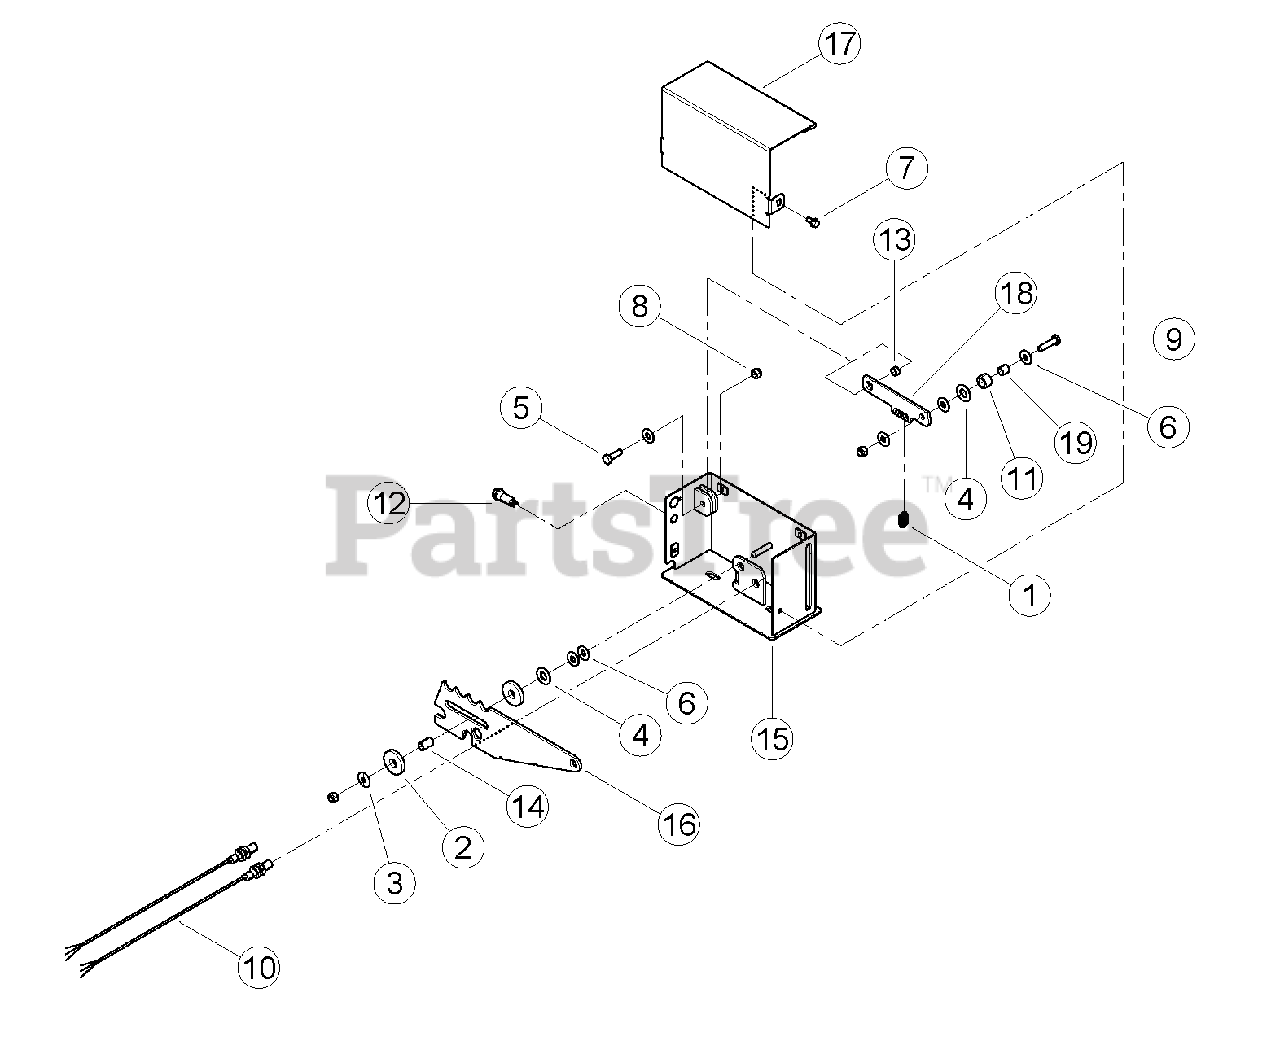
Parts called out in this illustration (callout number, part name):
1	SPRING, CONTROL BAR
2	WASHER, UHM SPACER .515 ID X 1.50 OD
3	WASHER, SPRING
4	WASHER, 1/2 SAE FLAT ZP
5	BOLT, 5/16 X 1 HHCS GR5 NC ZP
6	WASHER, 5/16 FLAT ZP
7	BOLT, 1/4 X 1/2 SERRATED FLANGE GR5 ZP
8	NUT, 5/16 NYLOCK
9	BOLT, 5/16 X 1-1/4 HHCS GR5 NC ZP
10	SENSOR, PROXIMITY (REPLACEMENT PART)
11	ROLLER, NYLON .750 OD X .502 ID X .440
12	LED, TRI-COLOR 12V 3-TERMINAL BASE
13	SPACER, IDLER PIVOT
14	SPACER, .50 X .775
15	WELDMENT, SWITCH BOX
16	BAR, SWITCH CONTROL
17	COVER, CONTROL BOX
18	LINK, DETENT
19	SPACER, .50 OD X .35 ID X .47
